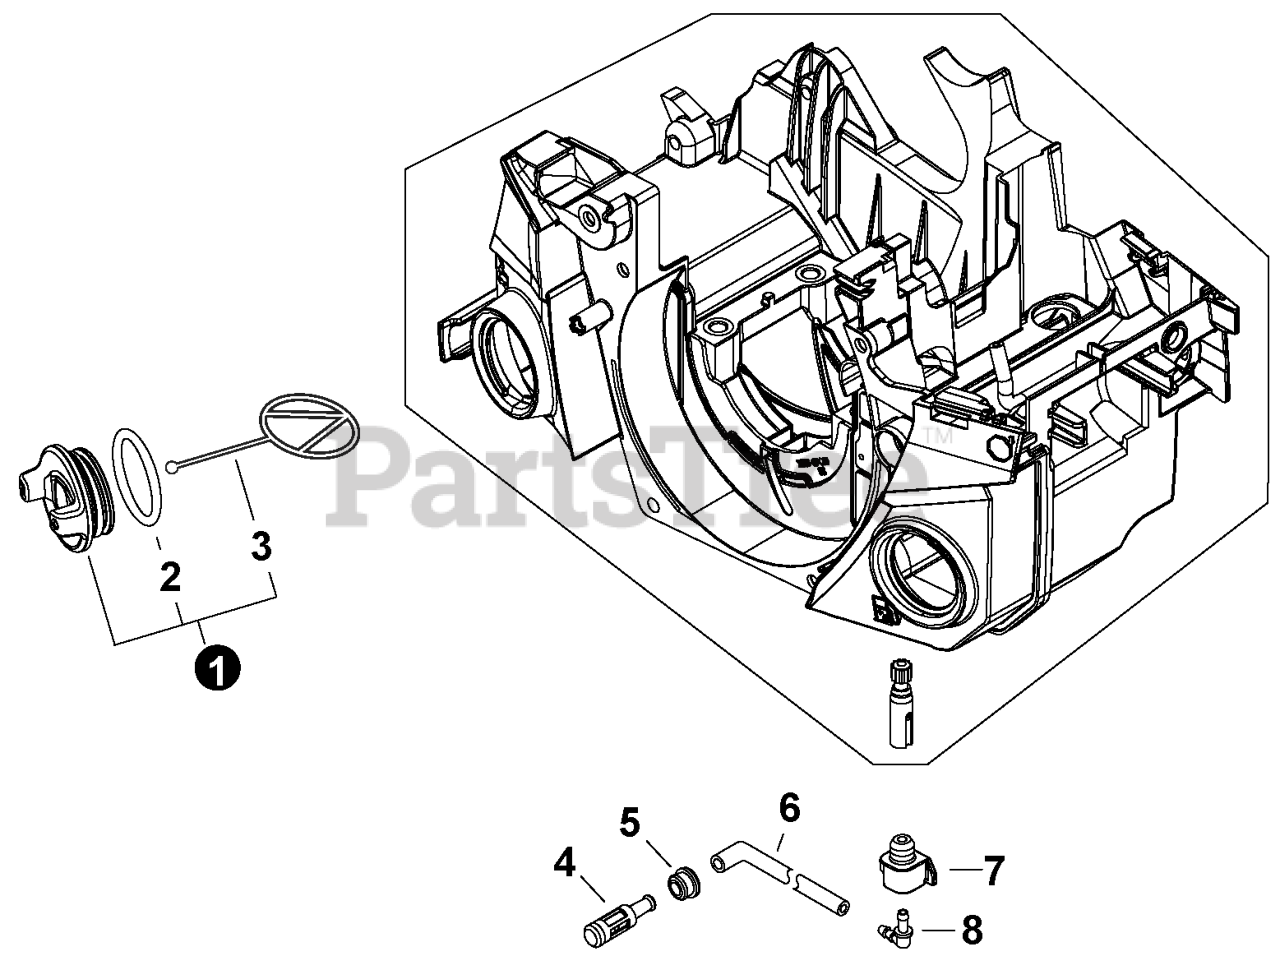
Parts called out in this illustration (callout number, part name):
1	CAP ASSY, OIL
2	O-RING 29
3	CONNECTOR, CAP L= 60 MM
4	FILTER, OIL
6	PIPE 3x6x210 BLACK
7	GROMMET, OIL
8	CONNECTOR, PIPE
